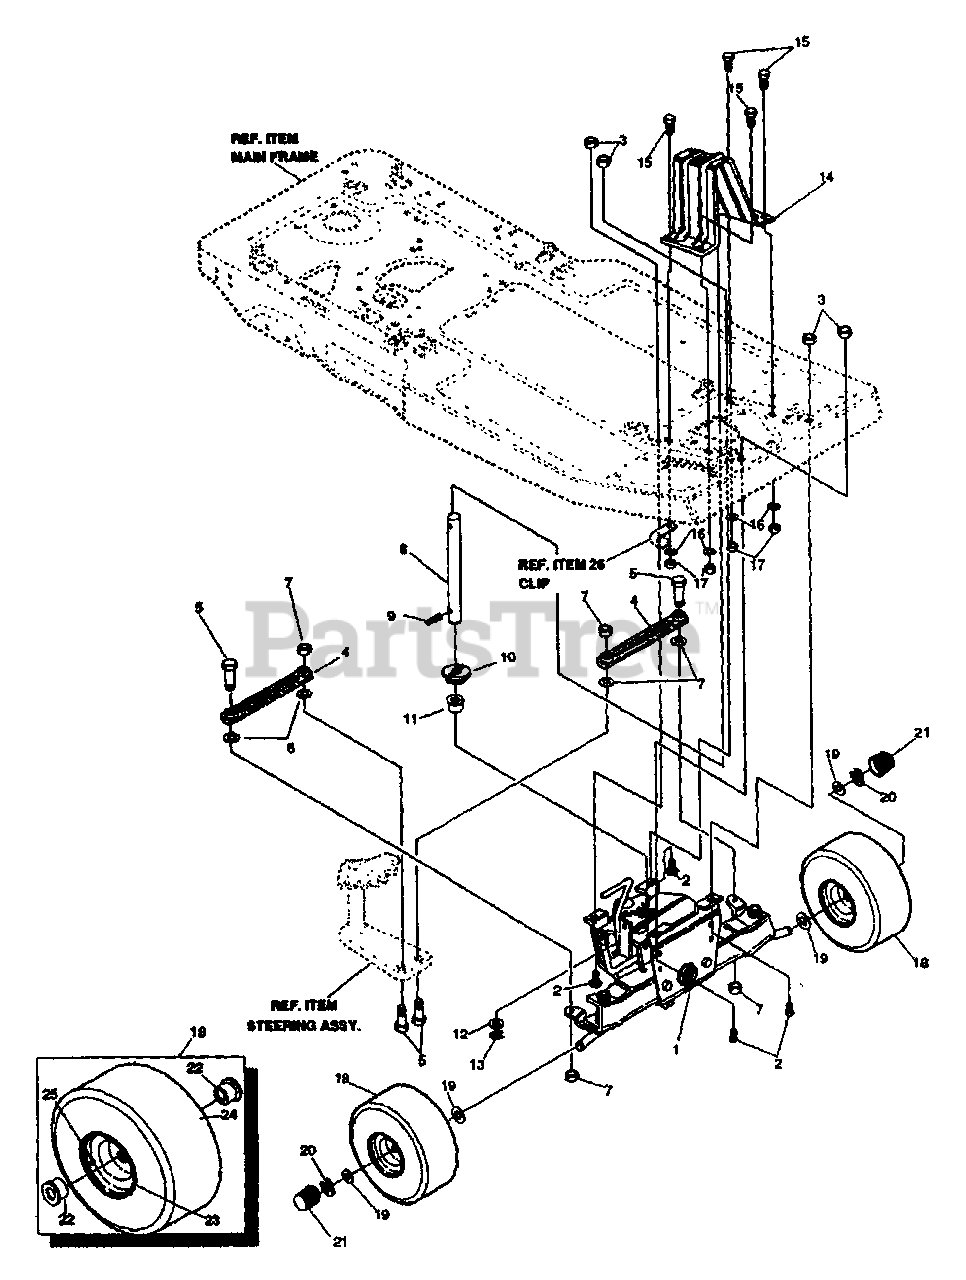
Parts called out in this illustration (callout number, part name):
1	Front Axle Assy.
2	Screw, 5/16-18 x .75 HHC GRD 2
3	Nut, 5/16-18 Hex Wd Fl Lk Whiz
5	Screw, 3/8-16 x 1.25 H HC GR2
6	Washer, Reg Spt Lk .393 x .68 x .10
7	Nut, 30-16 Reg Hx Ctr Lk
8	Shaft Steering
9	Pin, Spring .250 Dia x 1.25 Lg
10	Gear, Pinion
11	Bushing - Steering
12	Washer, Flat .635 x 1.31 x.07
13	Ring, Retaining E .48 x .04 TRU 5133-62
14	Support, Steering
15	Screw, 5/16-18 x .63 WA H HC GR2
16	Washer, Flat .344 x .69 x .065
17	Nut. 5/16-18 Reg Hex Ctr Lk
19	Washer, Flat .640 x 1.25 x .06
20	Ring, Retaining E .48 x .04 TRU 5133-62
22	Bearing, Wheel
24	Tire 11 X 4 - Turf
25	Valve Stem
26	Electrical System
